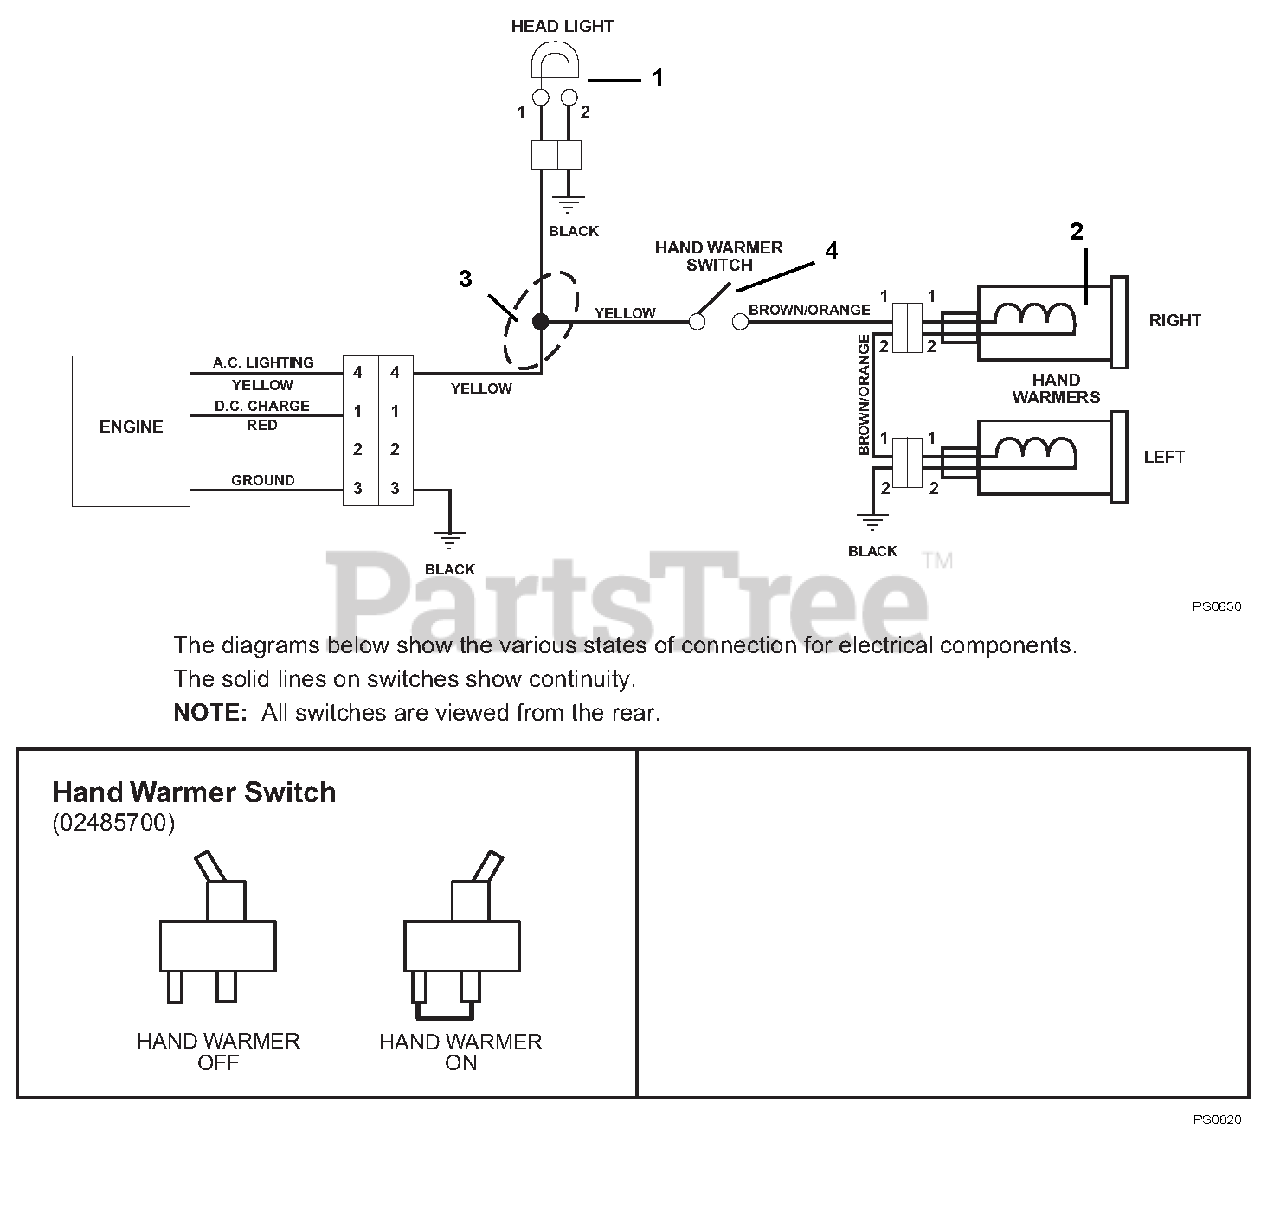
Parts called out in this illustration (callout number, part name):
1	LIGHT, HALOGEN ASSY.
2	HEATED GRIP, MAGURA
3	HARNESS, WIRE-LIGHT HANDWARMER
4	SWITCH, ON/OFF
